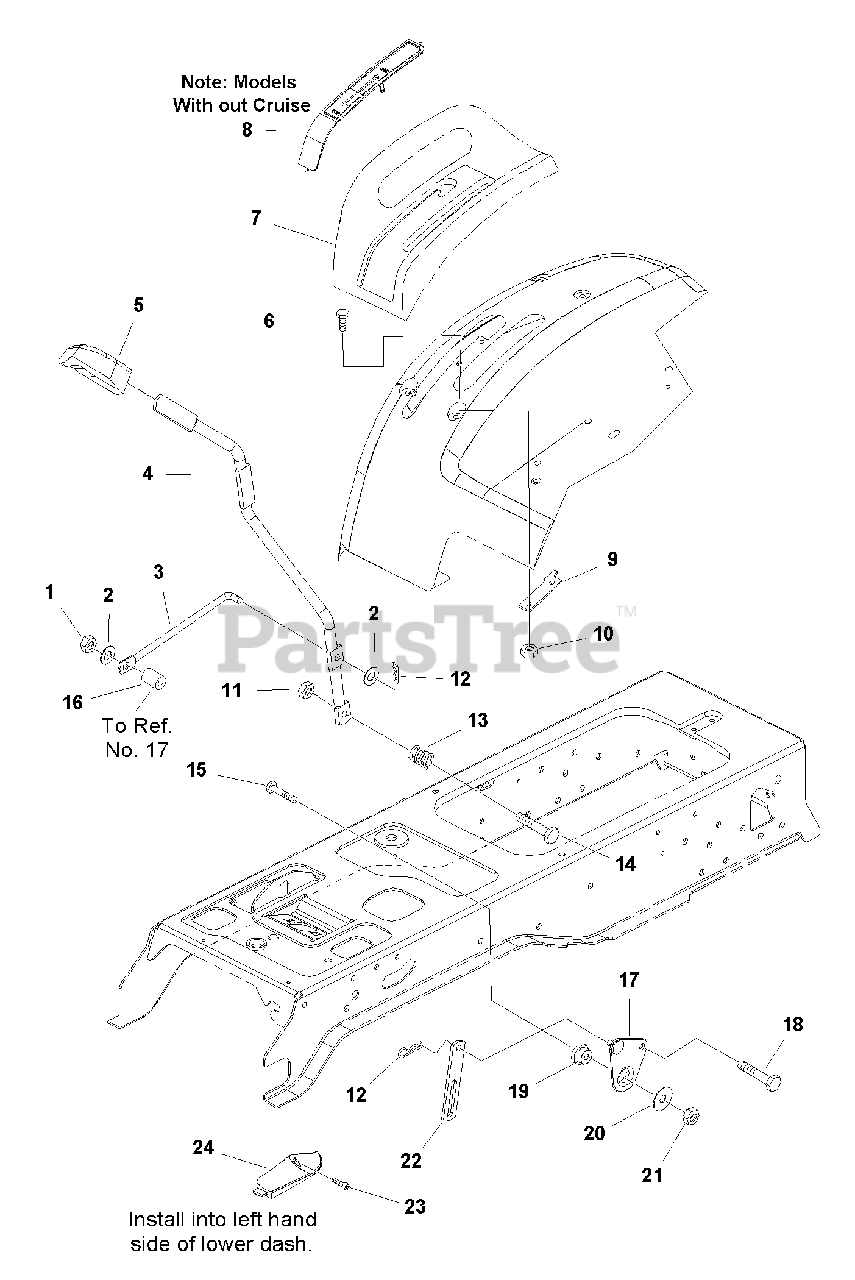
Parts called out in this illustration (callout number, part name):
1	NUT, Hex Lpck ESNA, 3/8-16
2	WASHER
5	GRIP, Black Vinyl
6	CAPSCREW, Hex Head, 1/4-20 x 3/4
7	POD, RH
8	COVER, W/Lift Icon, Models with out Cruise
10	NUT, Hex Lock ESNA, 1/4-20
11	NUT, Hex Flange Lock, 3/8-16
12	PIN, Quick
13	SPRING, Compression
14	CAPSCREW, Hex Head, 3/8-16 x 2
15	CAPSCREW, Hex Head, 5/16-18 x 1-1/4
17	CAM & RIN ASSEMBLY
18	CAPSCREW, Hex Head, 3/8-16 x 1-3/4
19	SPACER
21	NUT, Hex Lock, 5/16-18
22	LINK
23	SCREW, Torx Head, # 8-16 x 1/2
24	COVER, Dash
